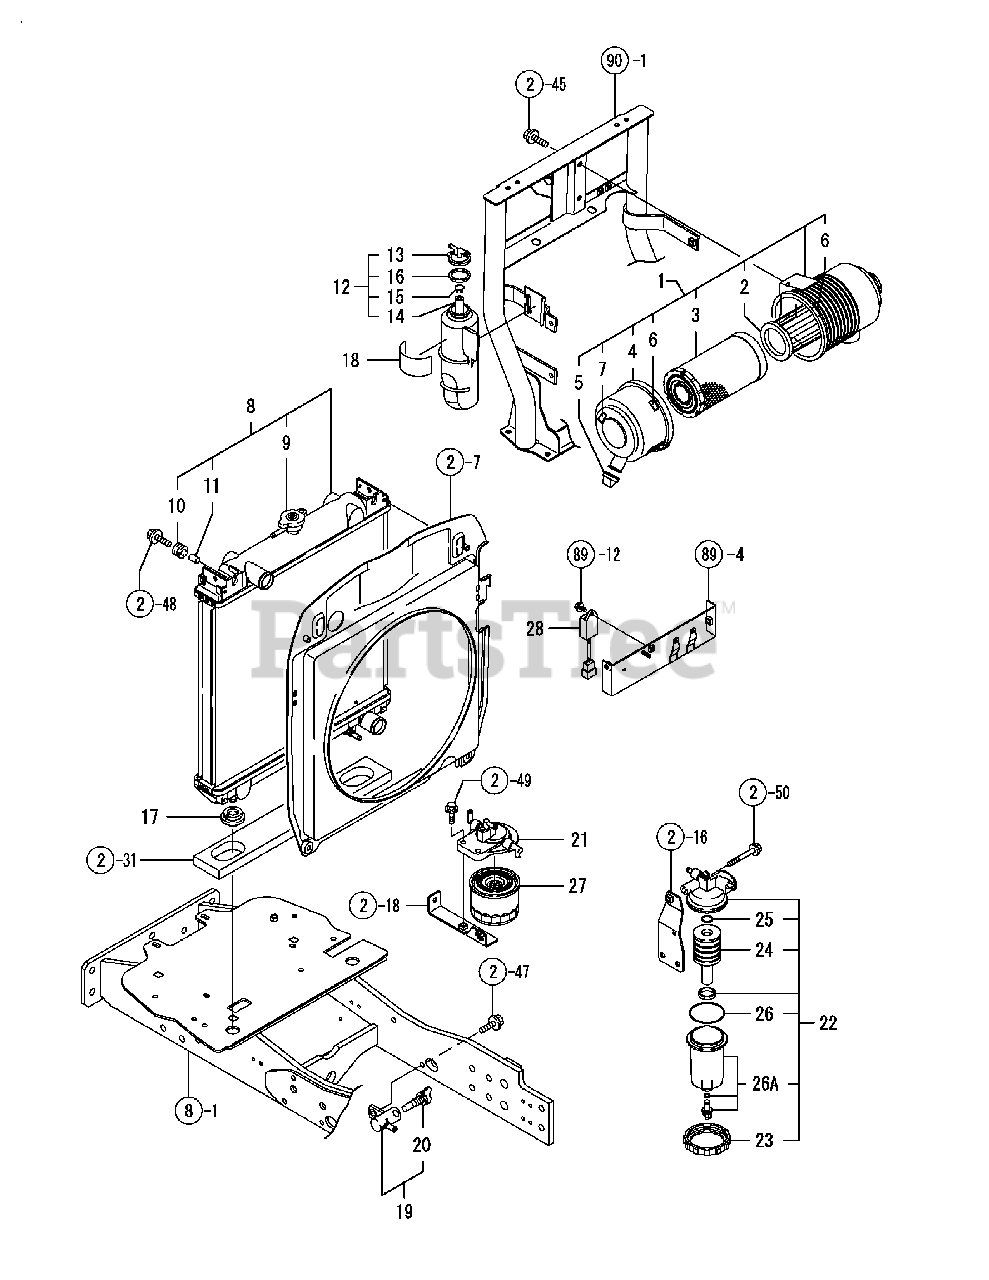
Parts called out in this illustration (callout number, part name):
1	CLEANER ASSY, AIR
2	ELEMENT, INNER
5	VALVE, UNLOADER
8	RADIATOR T=36 CMP
12	TANK ASSY, SUB
18	LABEL, SUB-TANK
19	PETCOCK ASSY, 2-WAY
20	PETCOCK, DRAIN
21	BRACKET, FILTER
22	SEPARATOR ASSY
23	RING, RETAINING
25	O-RING 1A P-16.0
26	O-RING 1A G-65.0
28	TIMER, FUEL SOLENOID 1 SEC
